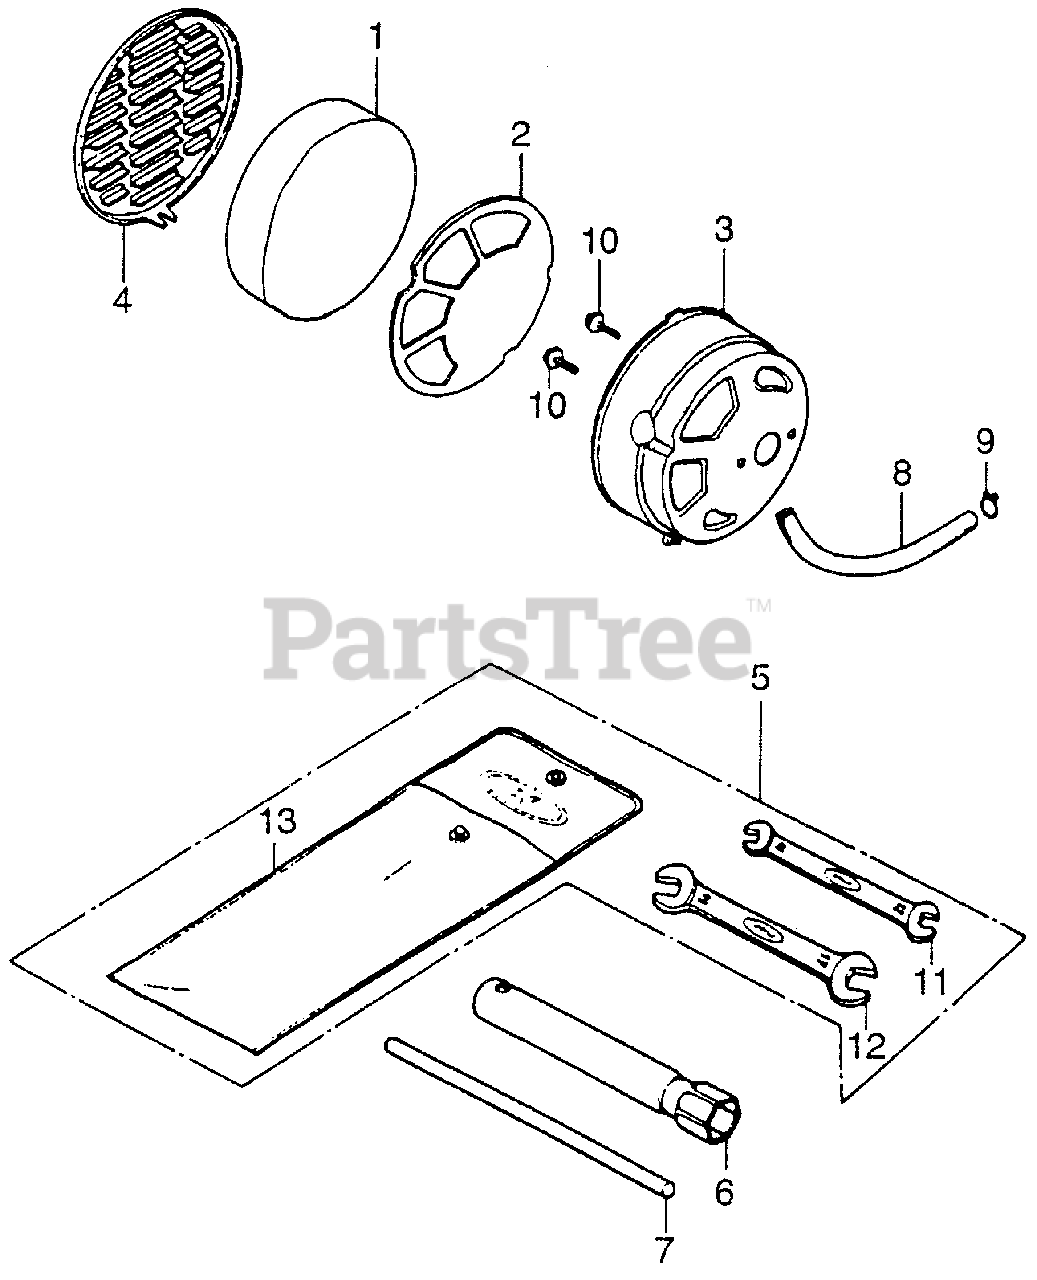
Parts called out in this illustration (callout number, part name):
1	ELEMENT, AIR CLEANER
2	GRID, AIR CLEANER (NOT AVAILABLE)
3	HOUSING, AIR CLEANER (NOT AVAILABLE)
4	COVER, AIR CLEANER
5	TOOL ASSY. (N/A: SEE COMPONENTS)
6	WRENCH, SPARK PLUG
7	HANDLE, BOX WRENCH (NOT AVAILABLE)
8	TUBE, BREATHER (NOT AVAILABLE)
8	TUBE (8X125) (NOT AVAILABLE)
9	CLIP, TUBE (B12.5)
10	BOLT, FLANGE (6X12)
11	WRENCH (10X12) (OPEN END)
12	WRENCH (14X17) (OPEN END)
13	BAG, TOOL
